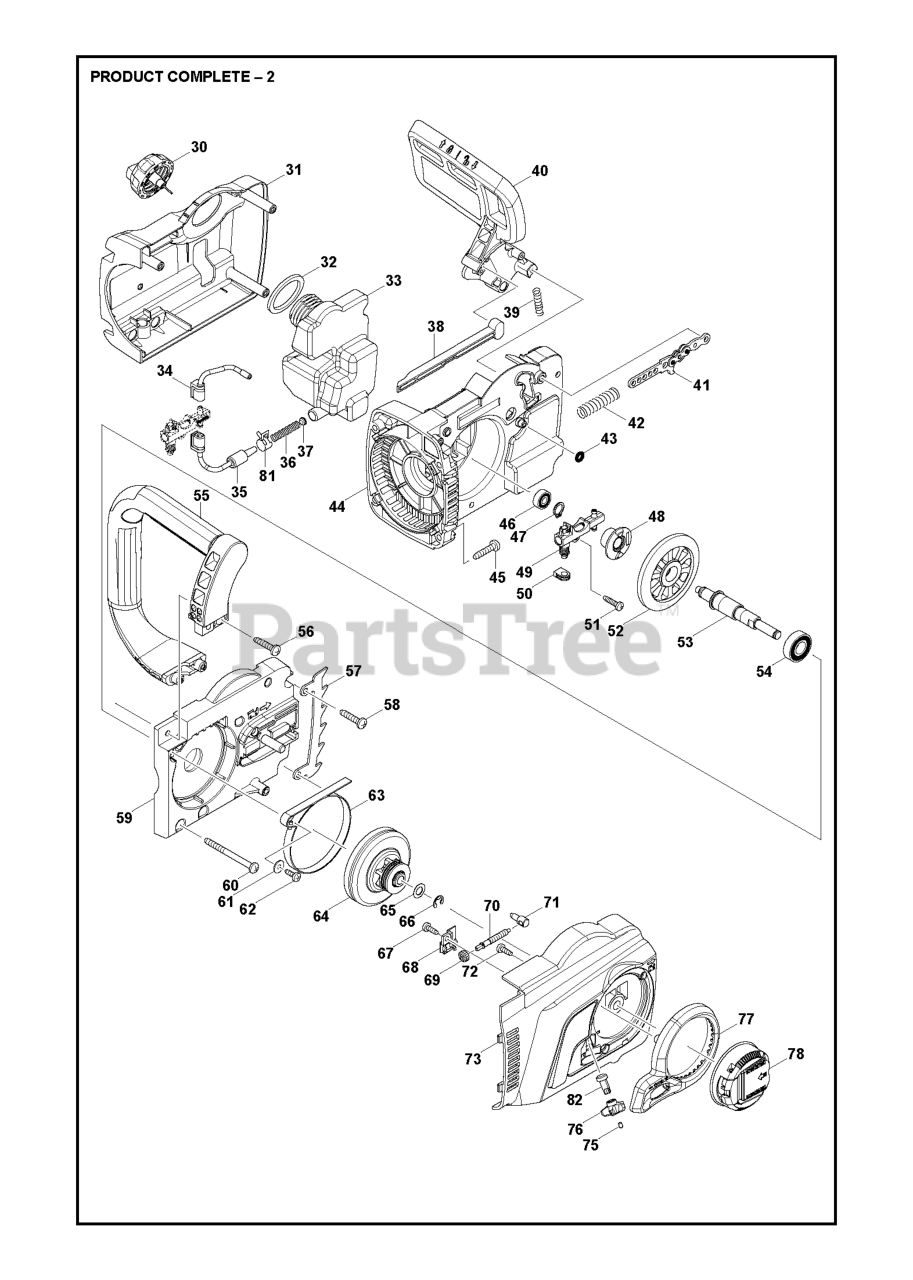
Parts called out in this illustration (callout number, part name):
1	HEXAGON NUT PART FOR 414EL/418
2	GEAR PART FOR 414EL/418EL/420E
3	BALL BEARING PART FOR 414EL/41
4	FAN 80 PART FOR 414EL/418EL/42
6	WASHER PART FOR 414EL/418EL/42
7	BALL BEARING PART FOR 414EL/41
8	SCREW PART FOR 414EL/418EL/420
9	BAFFLE PLATE PART FOR 414EL/41
11	SWITCH PART FOR 414EL/418EL/42
12	MOTOR HOUSING PART FOR 414EL/4
14	SPRING PART FOR 414EL/418EL/42
15	BUTTON PART FOR 414EL/418EL/42
16	SWITCH PART FOR 414EL/418EL/42
17	SCREW PART FOR 414EL/418EL/420
18	HANDLE PART FOR 414EL/418EL/42
21	CLAMP PART FOR 414EL/418EL/420
22	SCREW PART FOR 414EL/418EL/420
25	SWITCH PART FOR 414EL/418EL/42
26	CARBON BRUSH PART FOR 414EL/41
27	CAP 418EL,420EL,414EL
28	HANDLE PART FOR 414EL/418EL/42
29	SCREW PART FOR 414EL/418EL/420
